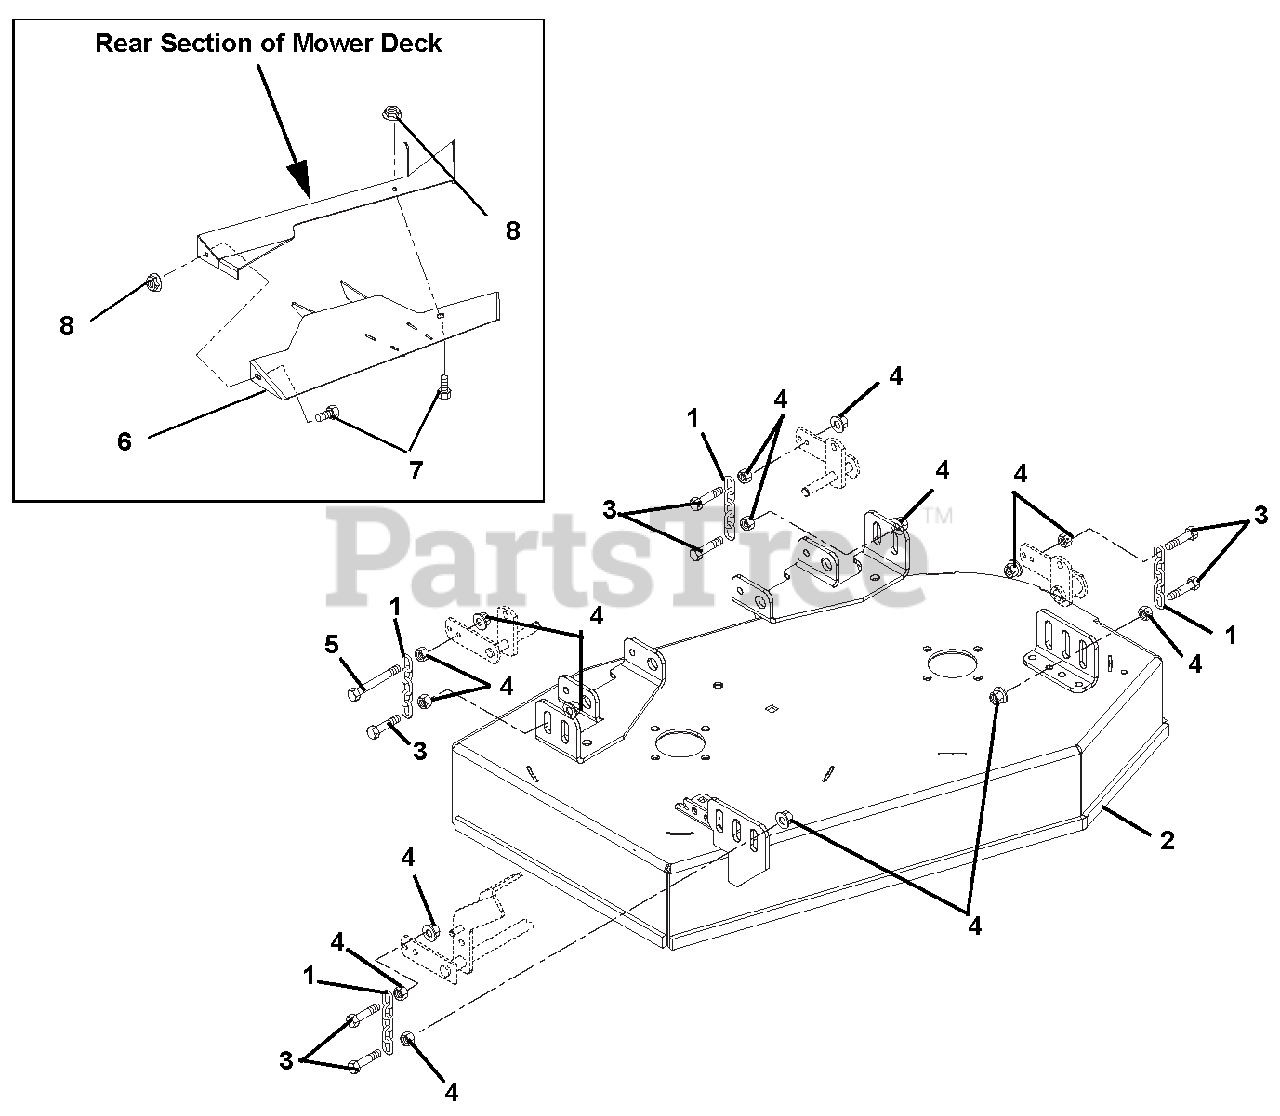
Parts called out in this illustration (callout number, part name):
1	CHAIN, LINK
2	WMT-34" MOWER DECK-REAR DISCH
3	BLT, HEX M12-1.75X50 CLS8.8 YZ
4	NUT-SPNLK-FLG M12-1.75 YZ
5	@BLT-HEX .50-13X3.00 GR5 YWZC
6	WMT-34" DEFLECT EXT-REAR DISCH
7	BLT-HEX .31-18X1.0 YWZC
8	@NUT-LK-TOP-FLG .31-18 YWZC
